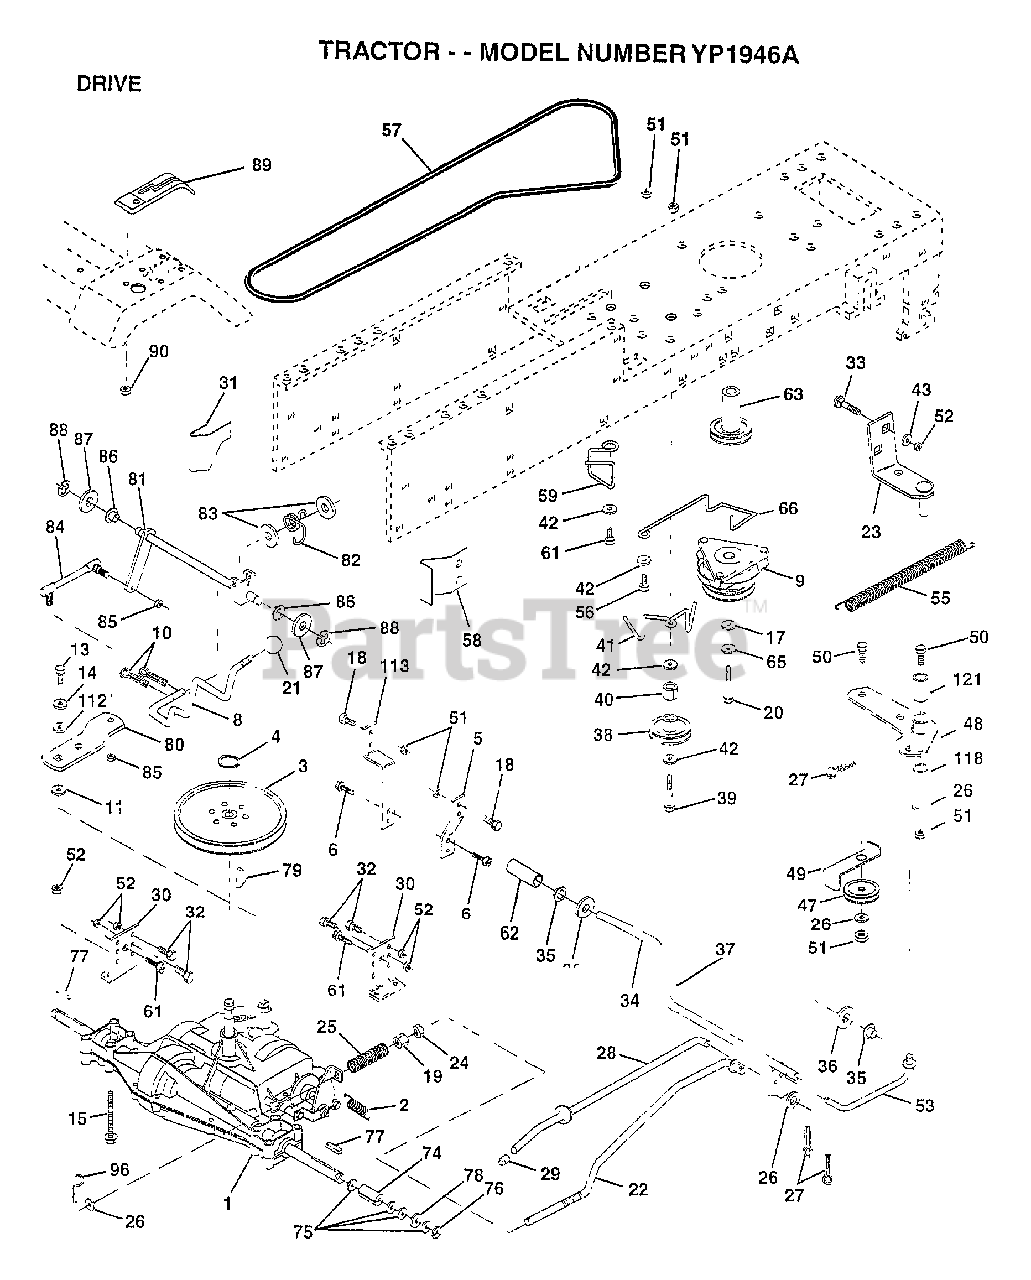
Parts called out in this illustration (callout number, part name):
1	TRANSAXLE, PEERLESS
2	SPRING.BRAKE.RETU
3	PULLEY TRANS
5	STRAP TORQUE
6	SCREW
8	ROD SHIFT FEND YT
10	PIN COTTER 1/8
11	WASH-SHFT PLT LT
13	BOLT.1/4-28.W/PAT
14	LOCKWASHER
15	BOLT.HX.FLG.5/16
17	WASHER
18	BOLT
19	NUT
20	BOLT.7/16-20X4.25
21	KNOB.DUCKHEAD.1/2
22	BRAKE ROD
23	BRACKET.ASM.MTG
24	NUT
25	SPRING ROD LT
26	WASHER
27	COTTER PIN
28	ROD.BRAKE.PARK.LT
29	PLUNGER CAP T
30	TRANSAXLE MTG BKT
31	"KEEPER,BELT LH T"
32	BOLT
33	BOLT
34	SHAFT ASM-PEDAL F
35	NYLON BEARING
36	WASHER LT
38	PULLEY.IDLER.FLAT
39	BOLT
40	SPACER T
42	WASHER
43	WASHER T
48	BELLCRANK ASM
49	RETAIN BELT
53	"LINK, CLUTCH T"
55	"SPRING, RETURN LT"
59	KEEPER BELT CNTSP
61	SCREW
62	"COVER,PEDAL"
63	PULLEY CLU ELEC
65	LOCKWASHER
66	KEEPER-BELT
74	SPACER AXLE
75	WASHER
76	E-RING LT
77	SQUARE KEY
78	WASHER
80	"ARM.SHIFT.20""TIRE"
81	SHAFT.CROS.P930.
82	"SPRING,TORSION"
83	WASHER
84	"ROD.TIE.20""P930LT"
86	BUSHING
87	WASHER D
88	KLIP RING
89	CONSOLE SHIFT
90	NUT
96	RETAINER M
112	WASHER LT
113	"STRAP,TORQUE"
118	SPACER-BELLCRANK
121	NYLINER-CLUTCHING
